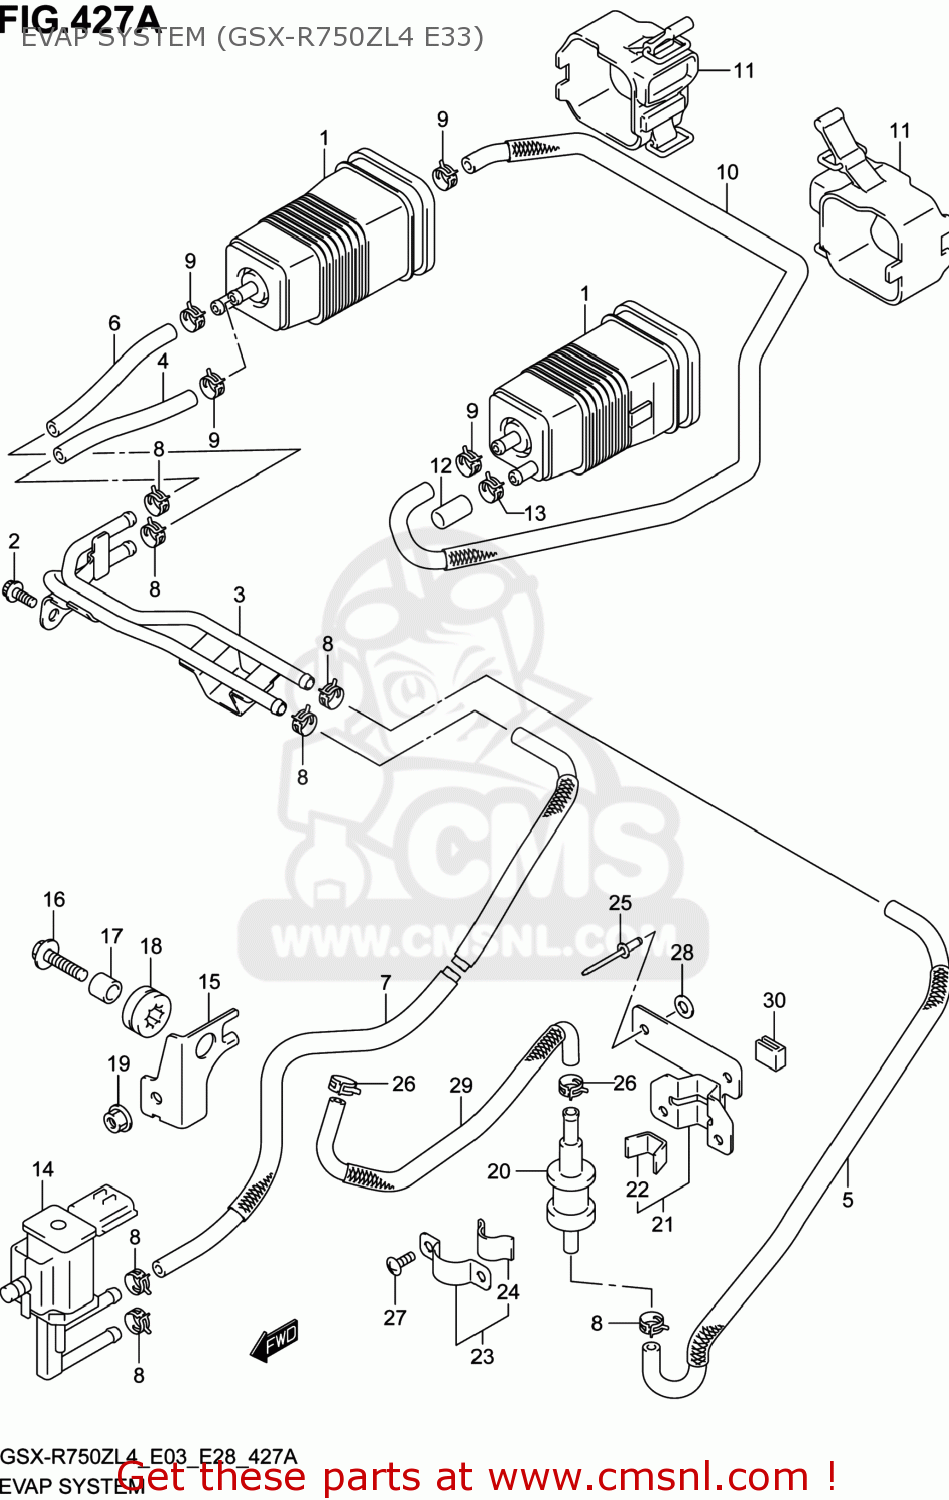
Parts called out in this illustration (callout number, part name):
1	CANISTER ASSY,CHARCOAL
2	BOLT
3	PIPE,EVAP
4	HOSE,SURGE NO.1
5	HOSE,SURGE NO.2
6	HOSE,PURGE NO.1
7	HOSE,PURGE NO.2
8	CLIP
9	CLIP
10	HOSE,CANISTER JOINT
11	CUSHION,CANISTER
12	CAP,OD:11.5
13	CLIP
14	VALVE ASSY,DUTY FOR PURGE
15	BRACKET,PURGE VALVE
16	BOLT(6X30)
17	SPACER(6.5X10X11.6)
18	CUSHION
19	NUT
20	VALVE,FUEL TANK BREATHER
21	PLATE,BREATHER VALVE
22	CUSHION
23	PLATE,FUEL TANK BREATHER NO.2
24	CUSHION
25	RIVET
26	CLIP
27	SCREW
28	WASHER
29	HOSE,TANK & BREATHER VALVE
30	CUSHION
